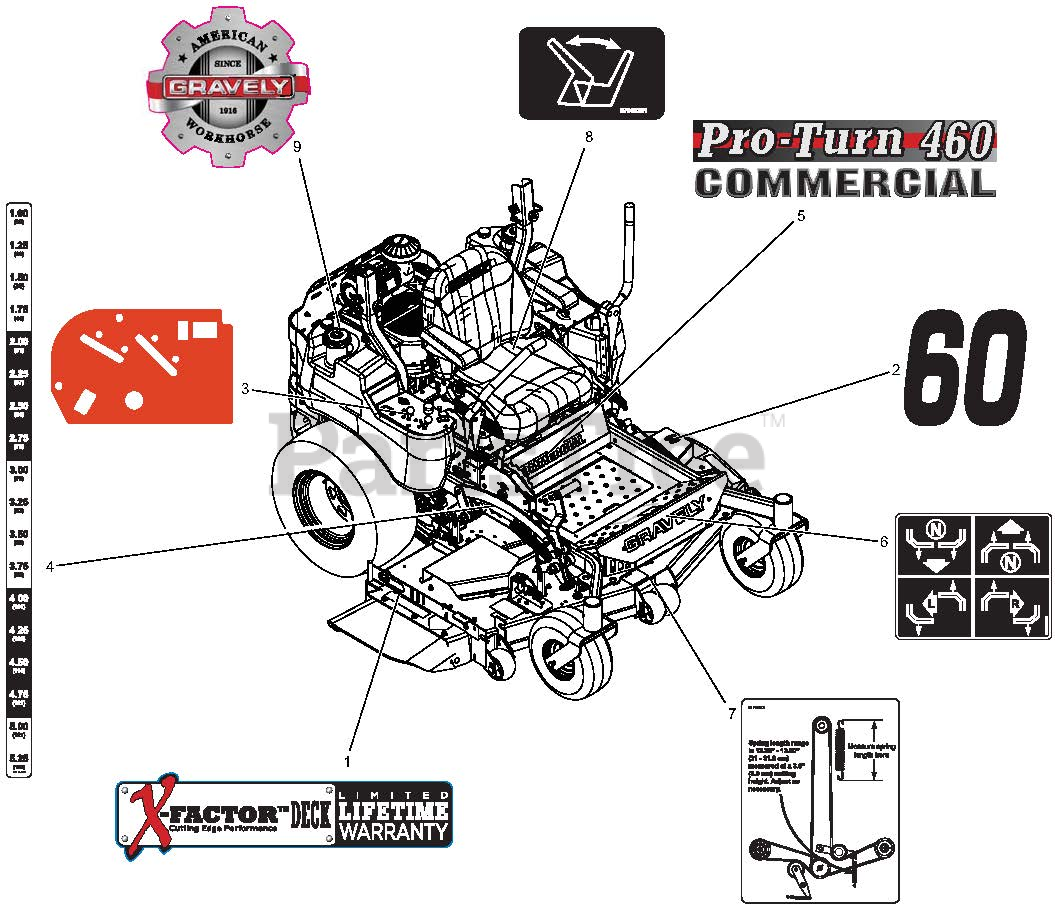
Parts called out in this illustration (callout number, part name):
1	DECAL, X-FACTOR DECK
2	DECAL, 60"
3	DECAL, NON-EFI CONTROL PANEL
4	DECAL, PT400 HEIGHT OF CUT
5	DECAL, PT460
6	DECAL, INSTRUCTIONAL - STEERING
7	DECAL, BELT DIAGRAM
8	DECAL, SEAT RELEASE
9	DECAL, GRAVELY HERITAGE-LARGE
